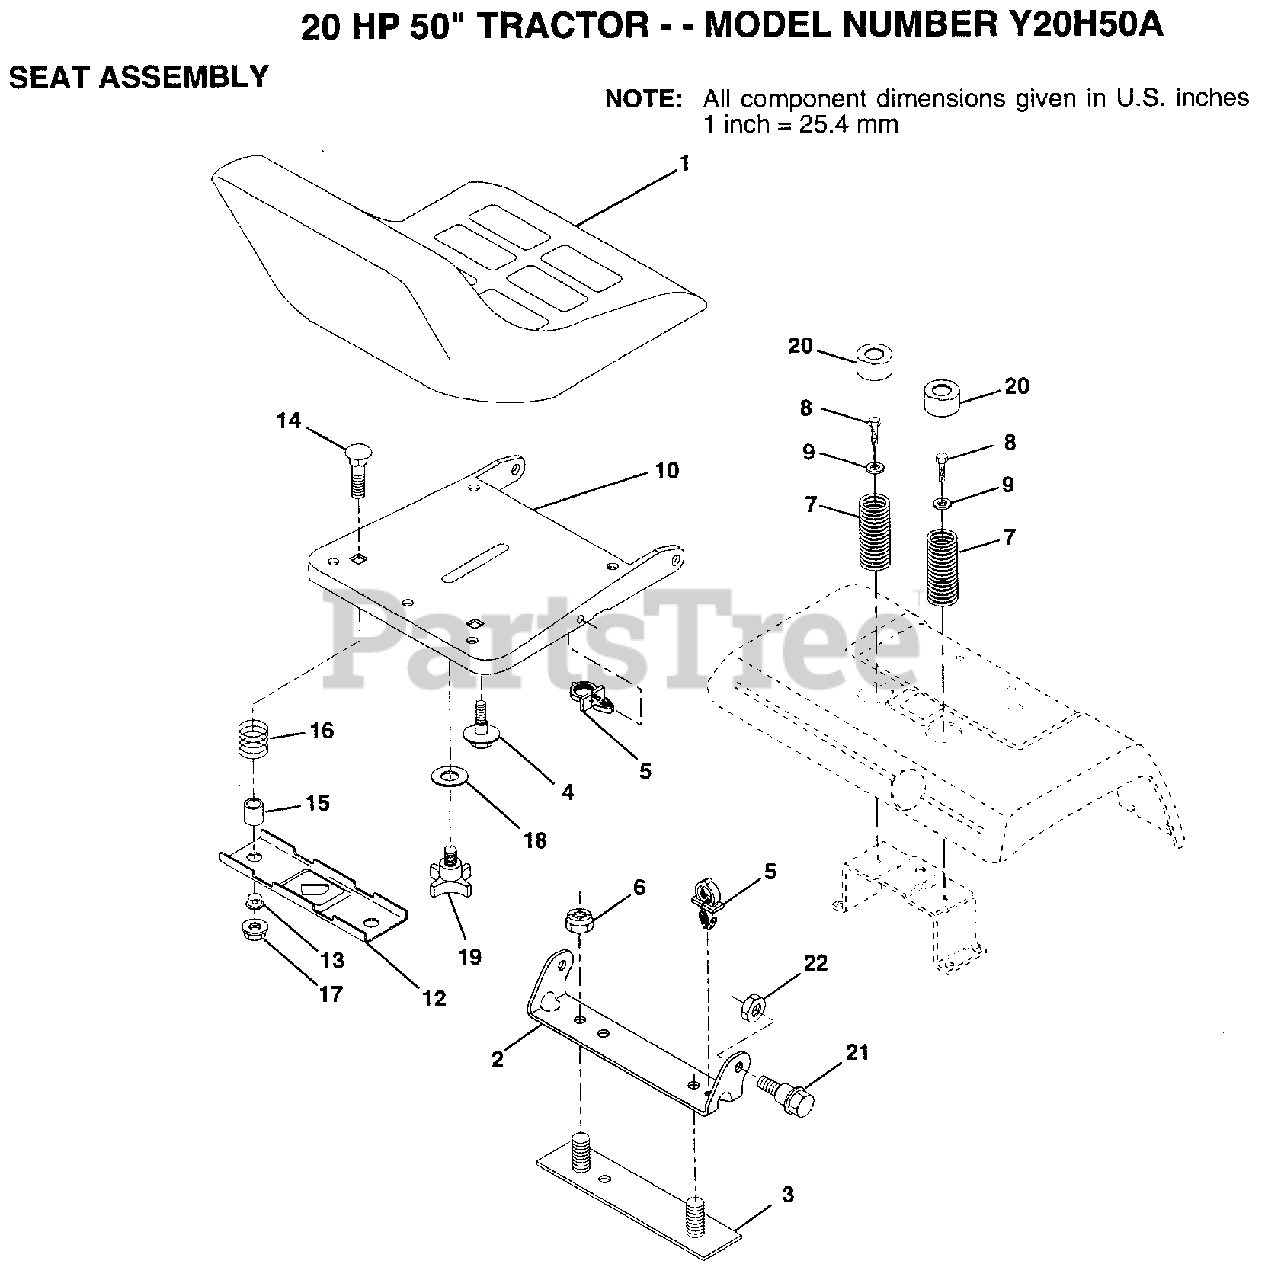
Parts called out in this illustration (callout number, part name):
2	BRACKET PVT SEAT
3	STRAP ASM FENDER
4	"BOLT,SHOULDER"
5	CLIP PUSH - IN
6	NUT
7	SPRING COMPRESSIO
8	SCREW LT
9	WASHER
12	BRKT SWITCH
13	BUSHING
15	SPACER SPLIT
16	SPRING COMPRESSED
18	WASHER
19	"KNOB 1/2"" YT"
20	CAP SPRING
21	BOLT.SHLD.5/16-18
